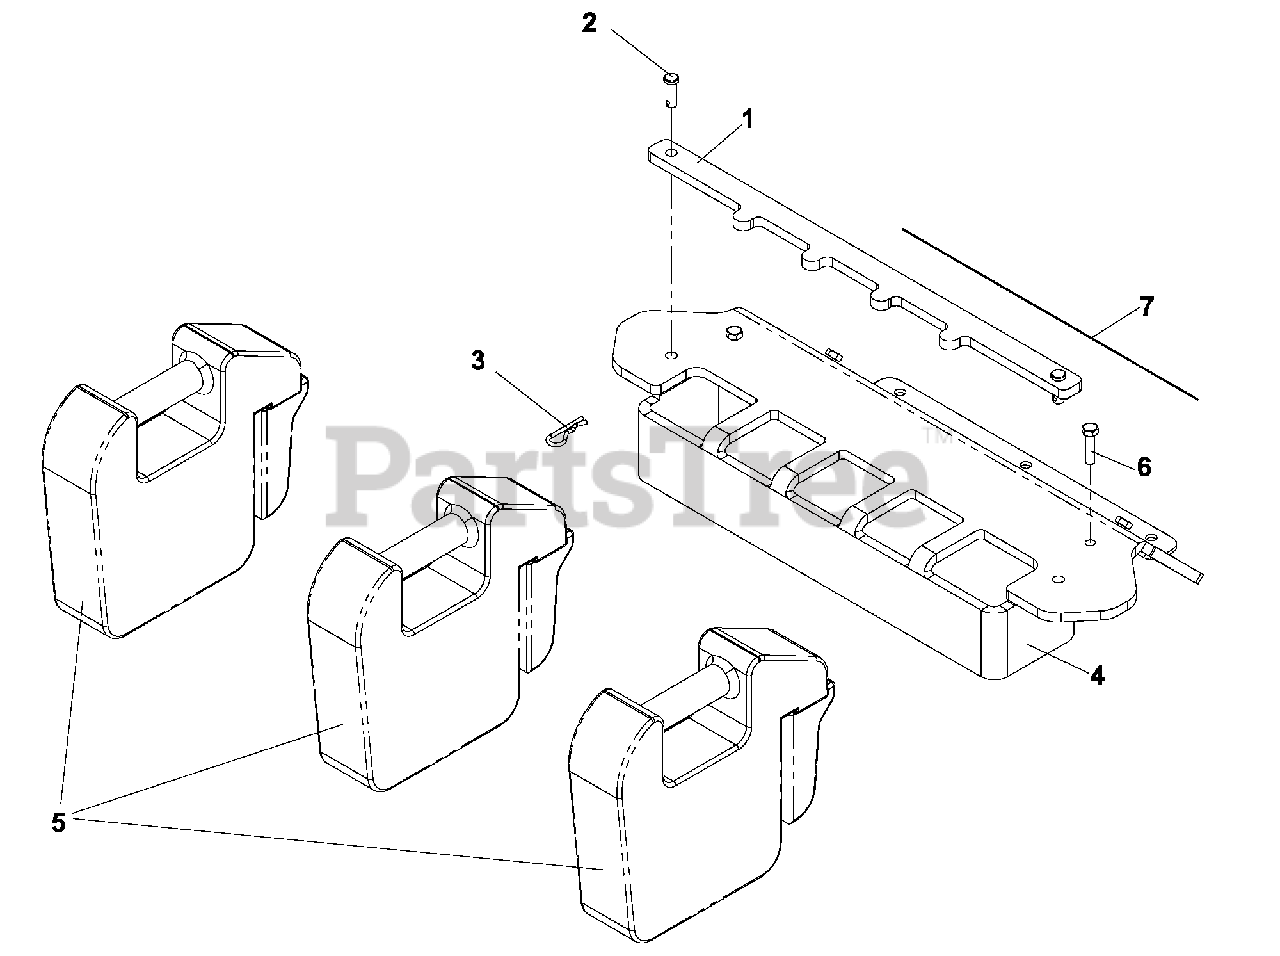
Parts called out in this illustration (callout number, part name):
1	HOLD DOWN, WEIGHT BAR
2	CLEVIS PIN
3	SPRING RETAINER
4	WEIGHT BAR
5	CAST COUNTERWEIGHT
6	HCS, 5/16-18 X 1 1/4, GR5
7	PAD, ABRASIVE
